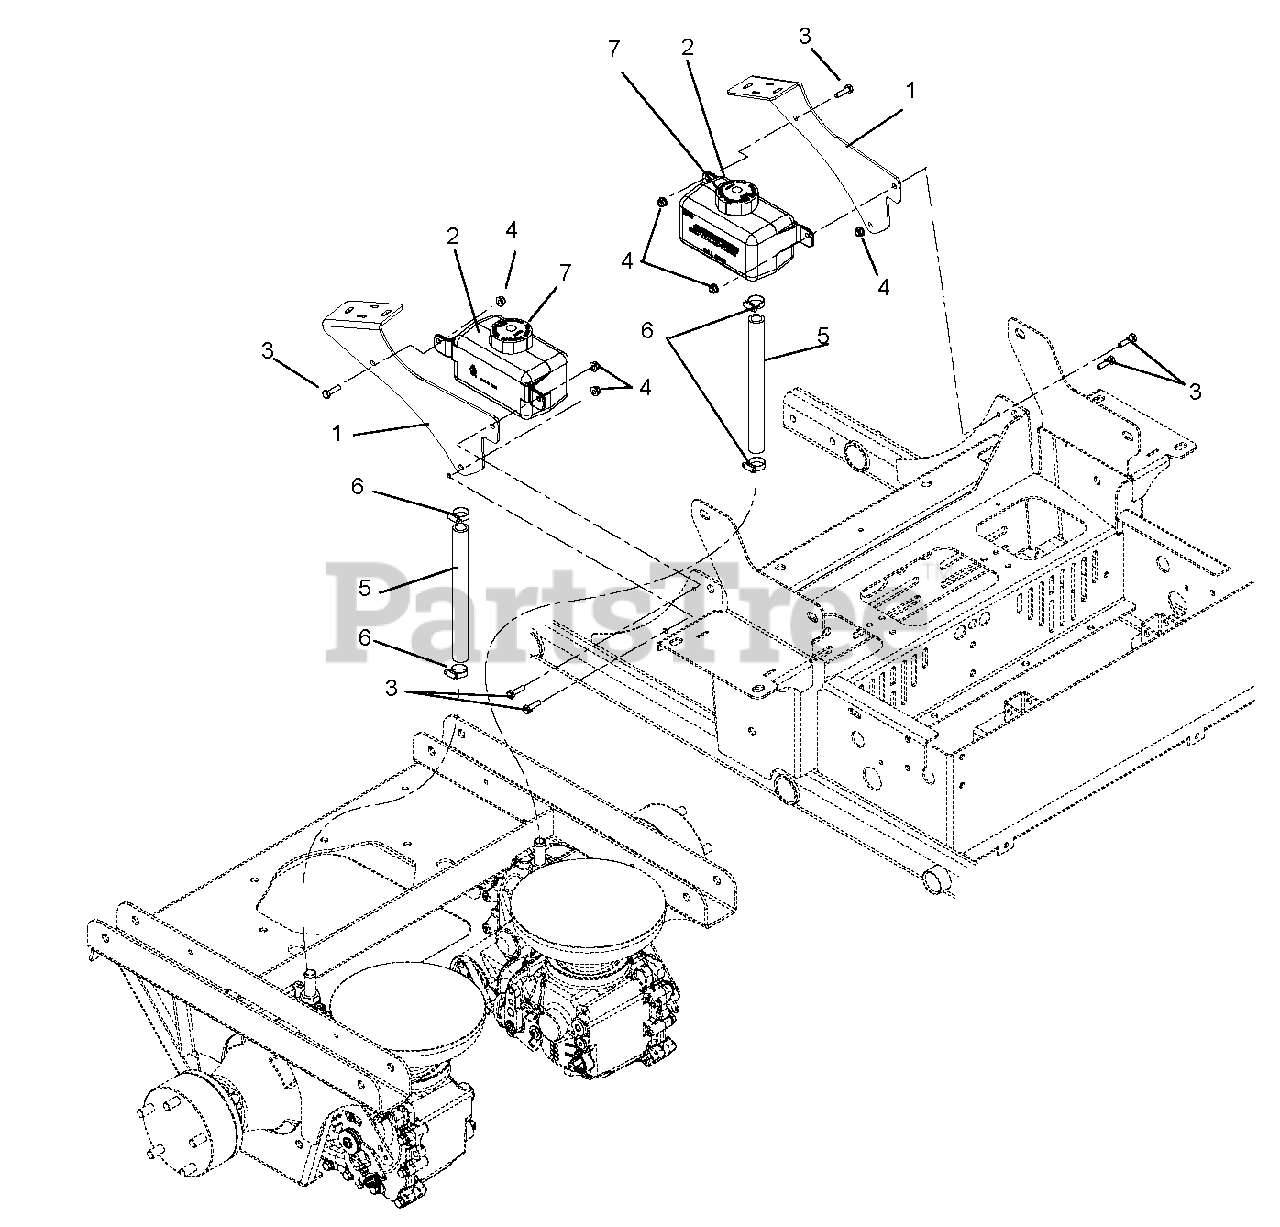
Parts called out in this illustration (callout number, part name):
1	Bracket, Canister Mounting Right Hand
2	Tank, Hydraulic 1000ML
3	Bolt, Hex .25-20 x 1.00 Grade 5 YWZC
4	Nut, Locking Nyloc Flange .25-20 YWZC
5	Hose, Hydro Overflow
6	Clamp, .88 DIA. Hose
7	Cap, Hydro Reservoir REPLAC.
8	Bracket, Canister Mounting Left Hand
